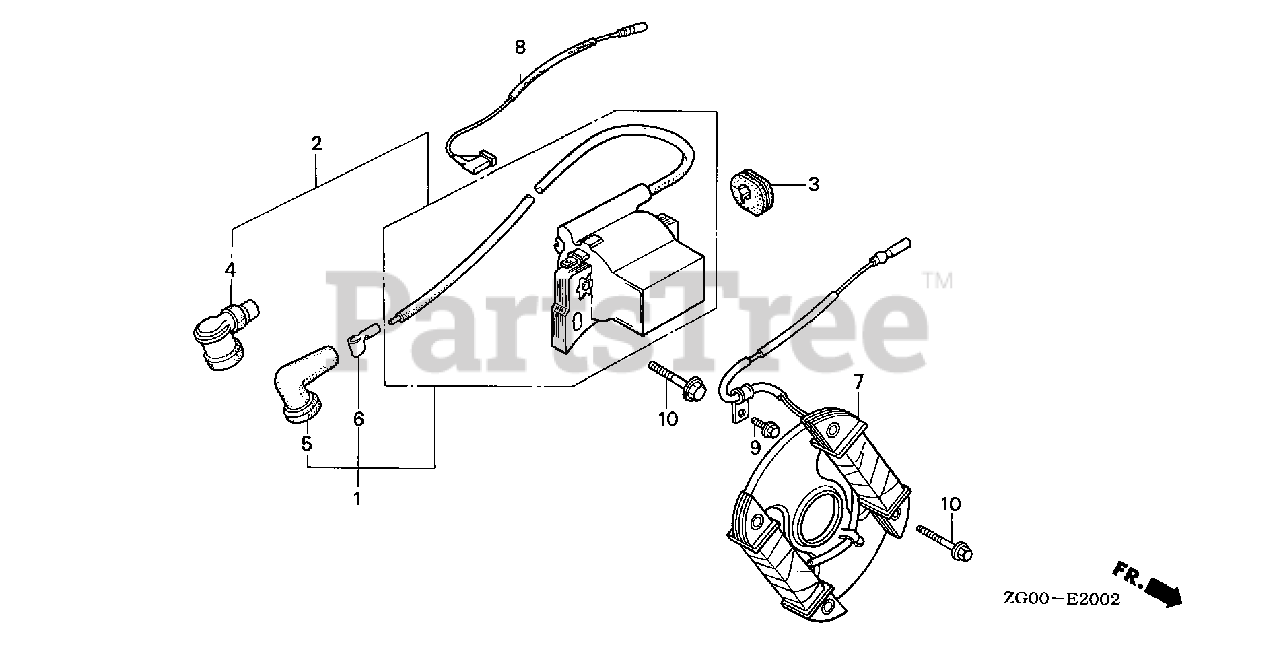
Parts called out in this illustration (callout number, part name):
1	COIL ASSY., IGNITION
3	GROMMET, IGNITION WIRE
5	CAP, IGNITION (TOYO)
6	TERMINAL, PLUG
8	WIRE, STOP SWITCH
10	BOLT, FLANGE (6X25) (CT200)
